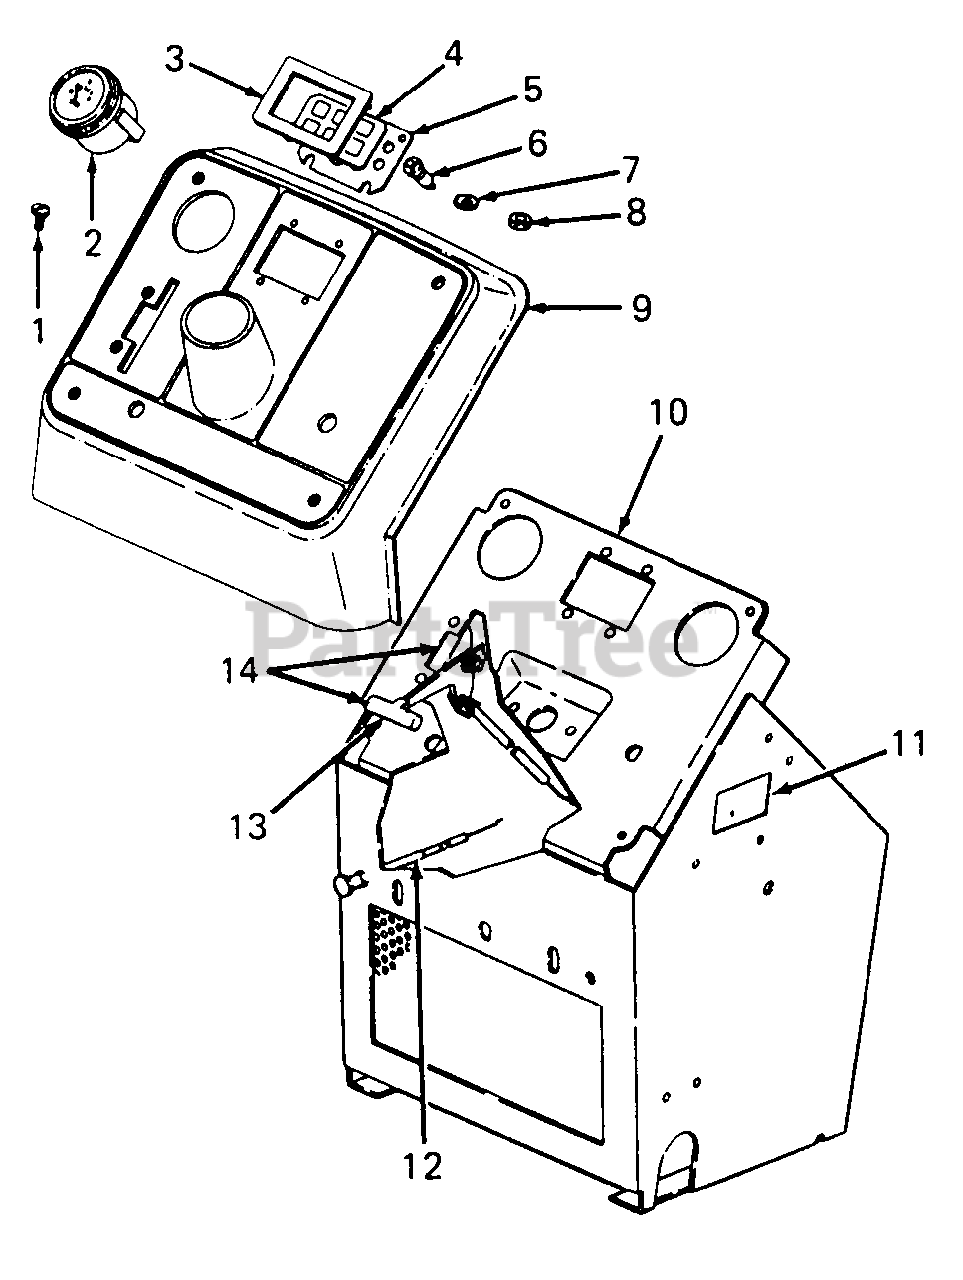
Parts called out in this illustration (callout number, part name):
1	Screw, 10-24 X 3/4 Pan-Hd. Cutting
2	Indicator, Charge
3	Bezel, Light
4	Label, Indicator
5	Plate, Indicator
6	Lamp, Indicator
7	Washer, .18 X .50 X. 06 Rubber
8	Nut, Self-Threading Pal
9	Panel, Instrument
11	Label, Battery Booster
12	Control, Choke
13	Knob, Throttle Control
14	Control, Throttle
